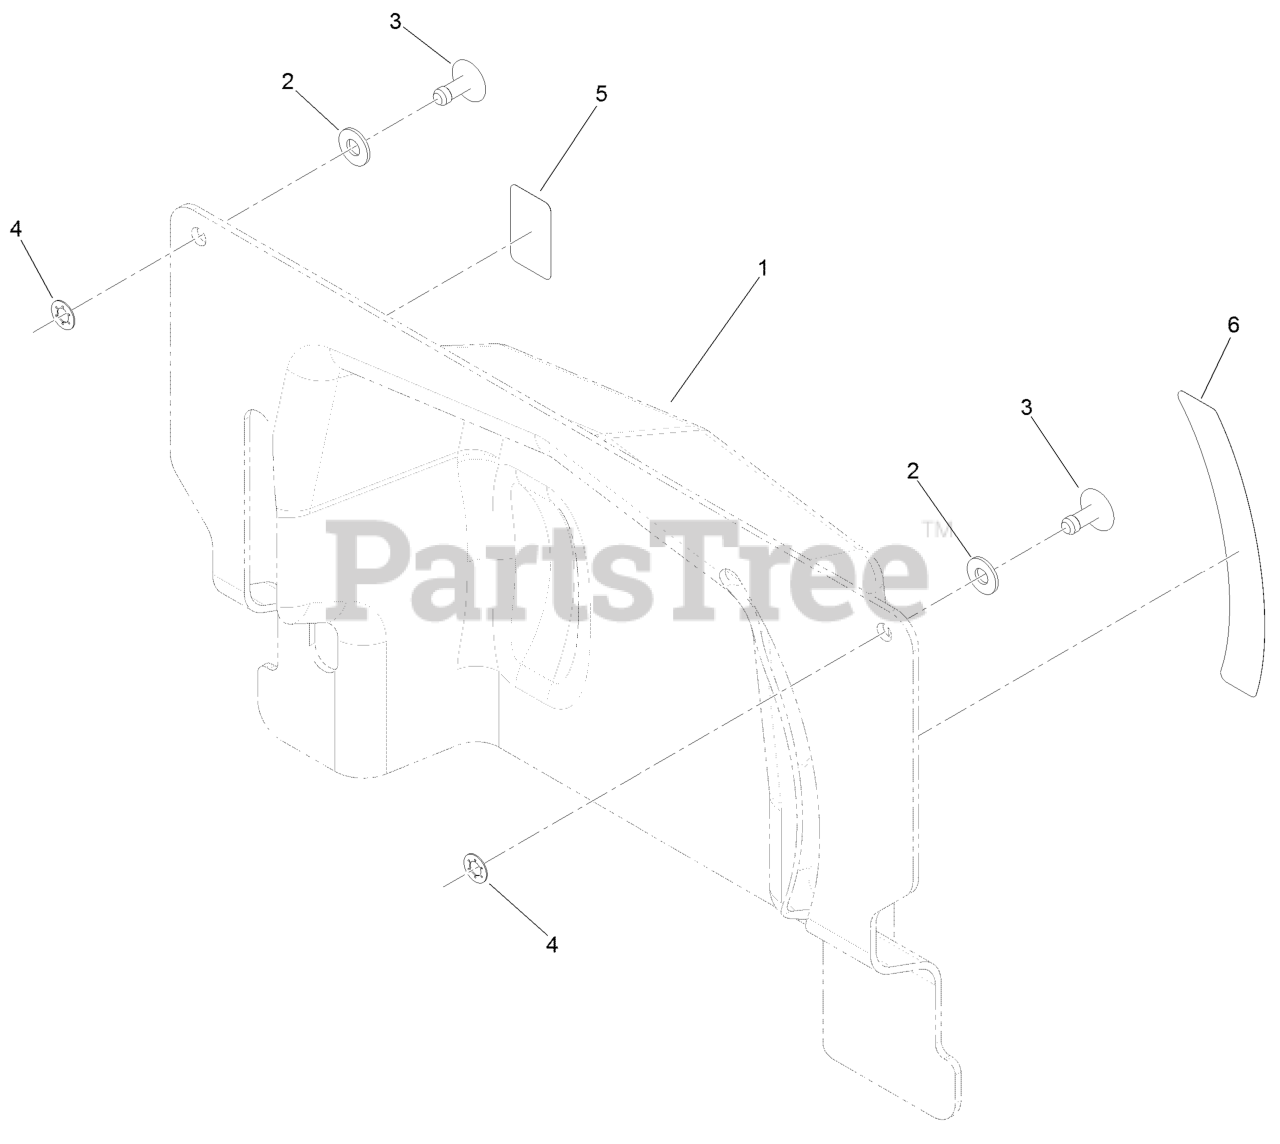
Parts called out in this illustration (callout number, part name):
1	Cover-Transaxle
2	WASHER-FLAT
3	STUD-1/4 TURN
4	RETAINER-STUD
5	DECAL-BRAKE, PARK
6	DECAL-RELEASE, DRIVE
